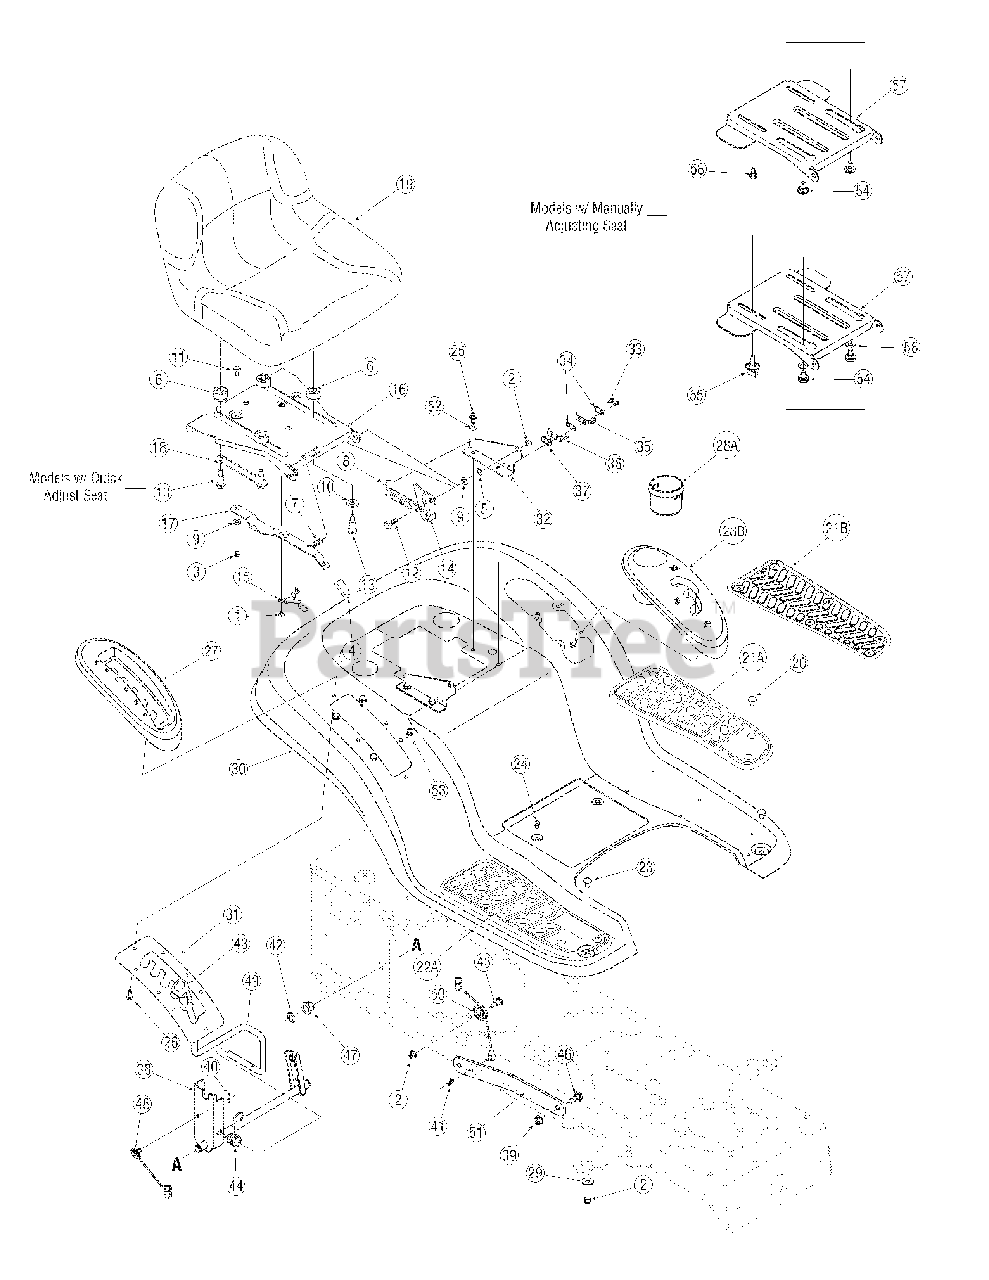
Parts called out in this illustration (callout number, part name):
1	Screw, #10-16 x.375 (if equipped)
2	Nut, Flange Lock, 5/16-18, GrF
3	Nut, Flange Lock, 1/4-20 (if equipped)
4	Seat Adjuster Grip (if equipped)
5	Nut, Speed,.3125 ID (if equipped)
6	Spacer (if equipped)
7	Compression Spring,.41 x 1.5 (if equipped)
8	Spring, Extension,.84 Dia. x 4.6
9	Wash, Flat,.344 x.688 x.065 (if equipped)
10	Wash, Flat,.531x 1.062 x.134 (if equipped)
11	Screw, Shld, .340 x.285, 1/4-20 (if equipped)
12	Screw, Shoulder,.437 x.268
13	Screw, Should,.50 x.925, 3/8-16 (if equipped)
14	Seat Bracket, Lift
15	Seat Stop (if equipped)
18	Seat Adjustment Selector (if equipped)
19	Medium Back Seat
20	Ratchet Clip
23	Bolt, Carriage, 5/16-18,.75, Gr1
24	Screw, 1/4-20, 0.500
25	Screw, 5/16-18, 0.625
26	Screw, 1/4-15, 0.750(if equipped)
27	Cover, Lift Lever (if equipped)
29	Washer, Flat,.344 x 1.0 x.063
31	Adjust. Brkt, Lift (Model X605H)
31	Adjust. Brkt., Lift
33	Screw, #8-18 x.50
34	Plate, Insulator
35	Spring Switch, Outer
36	Spring Switch, Inner
37	Plate, Insulator Boss
38	Shaft Assembly, Lift
39	Nut, Flange Lock, 3/8-16, GrF
40	Pin, Cotter,.072 Dia. x 1.13
41	Pin, Cotter, 3/32, 1.0
42	Ring, E Type,.625 Dia.
43	Grip, Handle, 1/2
44	Spring, Torsion
45	Screw, 5/16-18 x.620 Gr2
46	Scr.,Shldr, .625 x.165,(42" Deck)
46	Screw, Shld,.50 x.27, (46" Deck)
47	Bearing, Hex Flange
48	Cable, Lift, 16.16
49	Handle, Lift
50	Pulley, Roller
52	Lock Washer, 5/16
53	Scr5/16-18 x.750 (Model X605H)
53	Screw, 5/16-12
54	Shoulder Screw (if equipped)
55	Knob, 3/8-16 (if equipped)
56	Flat Washer, .406 x .875 (if equipped)
58	Hex Head Washer Screw, 3/8-16 (if equipped)
